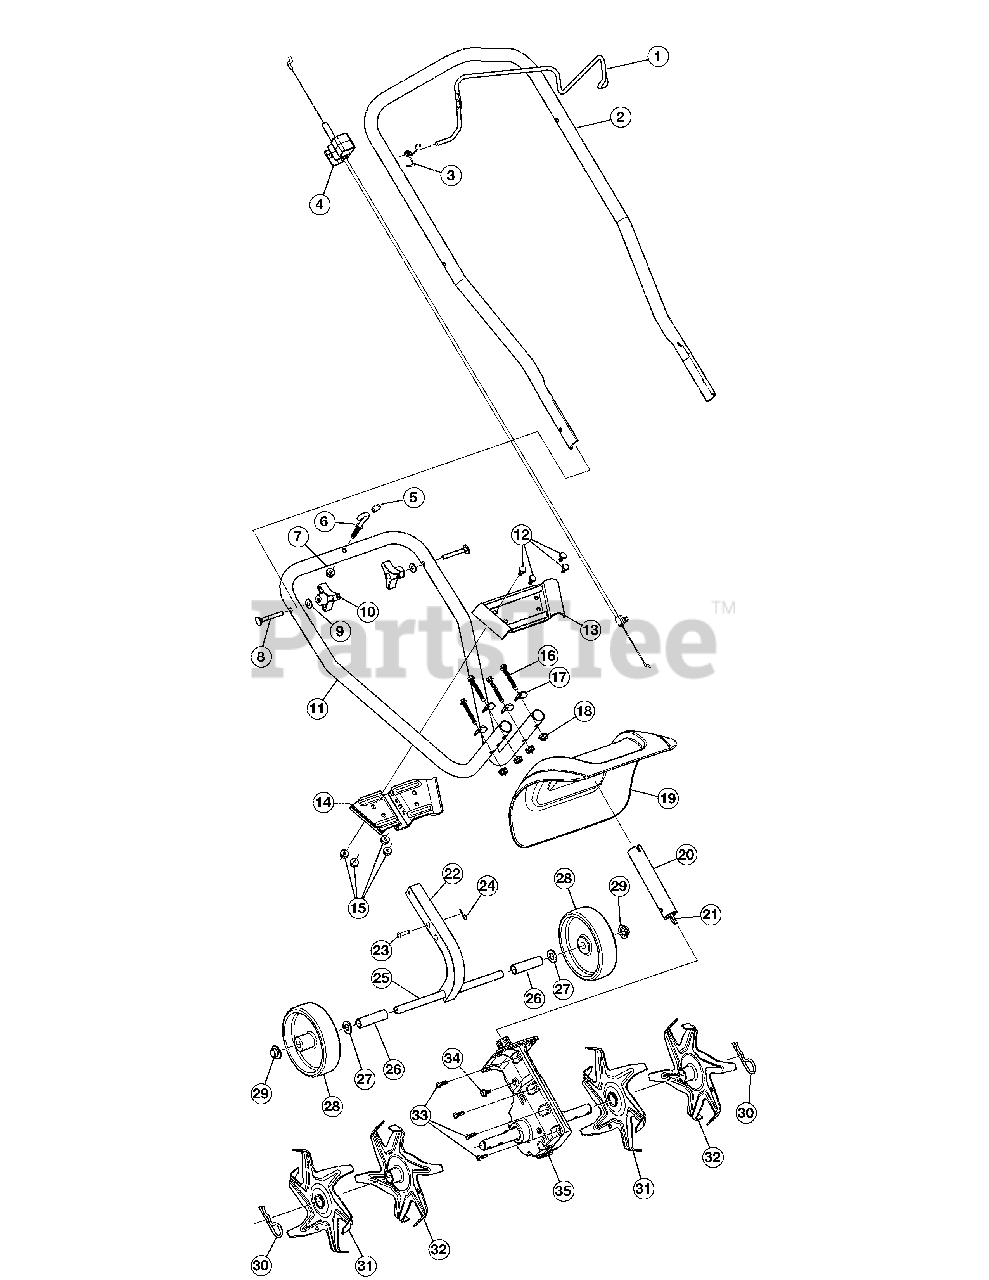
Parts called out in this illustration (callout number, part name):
1	Throttle
2	Handle
3	Spring
4	Throttle Cable
6	Rope Guide
9	Washer
11	Handle
12	Screw
13	Upper Bracket
14	Lower Bracket
17	Washer
19	Shield
20	Tube (Incl. 21)
21	Flex Shaft
22	Square Tube
23	Clevis Pin
24	Cotter Pin
26	Spacer
28	Wheel (Incl. 29)
31	Tine (Left Inner, Right Outer)
32	Tine (Left Outer, Right Inner)
34	Screw
35	Gearbox (Incl. 33)
